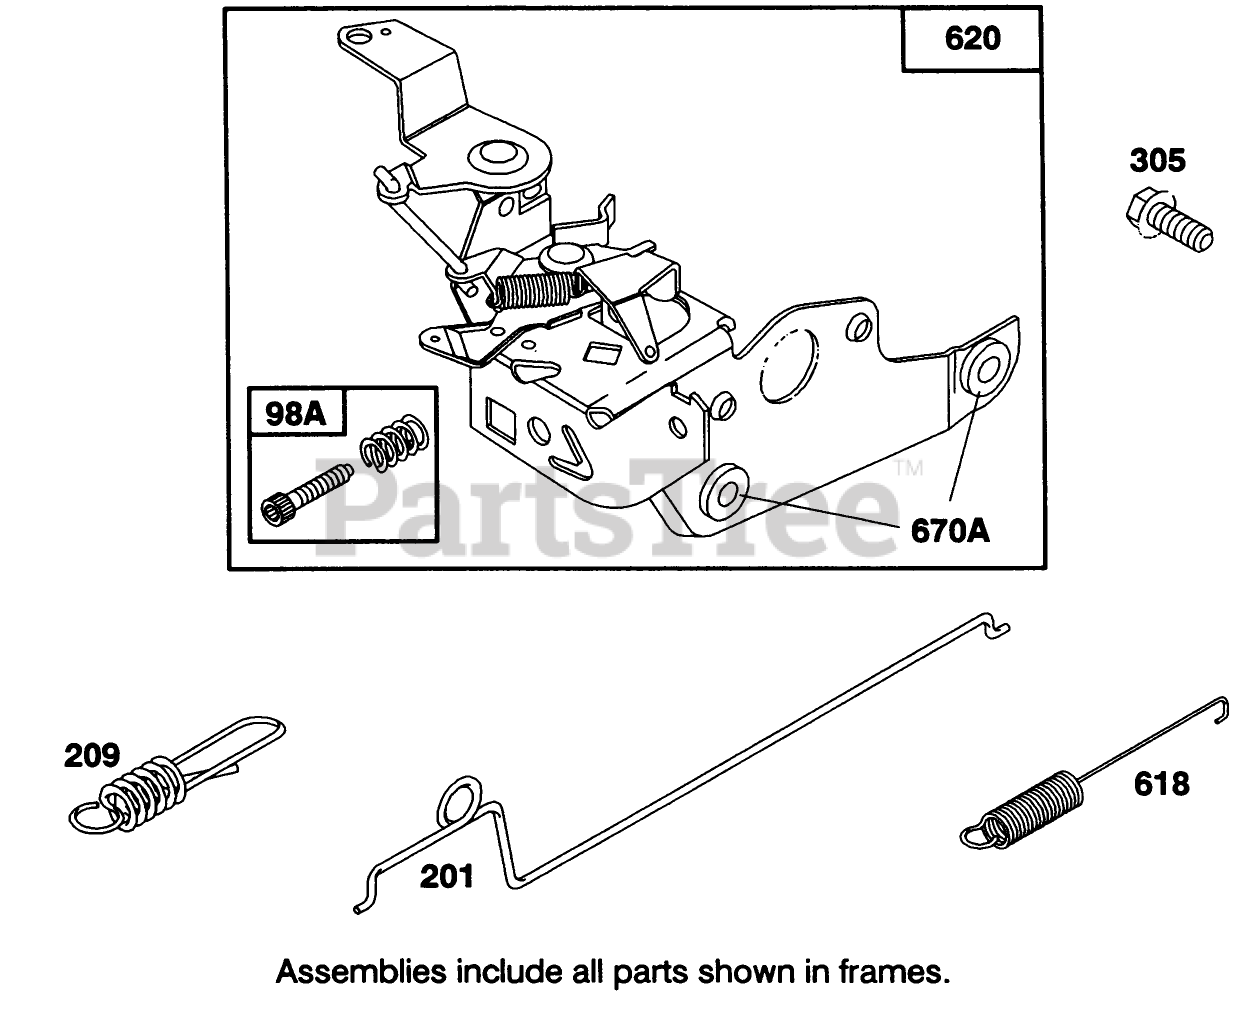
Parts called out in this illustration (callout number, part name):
98A	Screw Assy.
201	Link-Govemor
209	Spring-Govemor
305	Screw-Sem
618	Spring-Choke
620	Bracket Assembly
670A	Spacer
